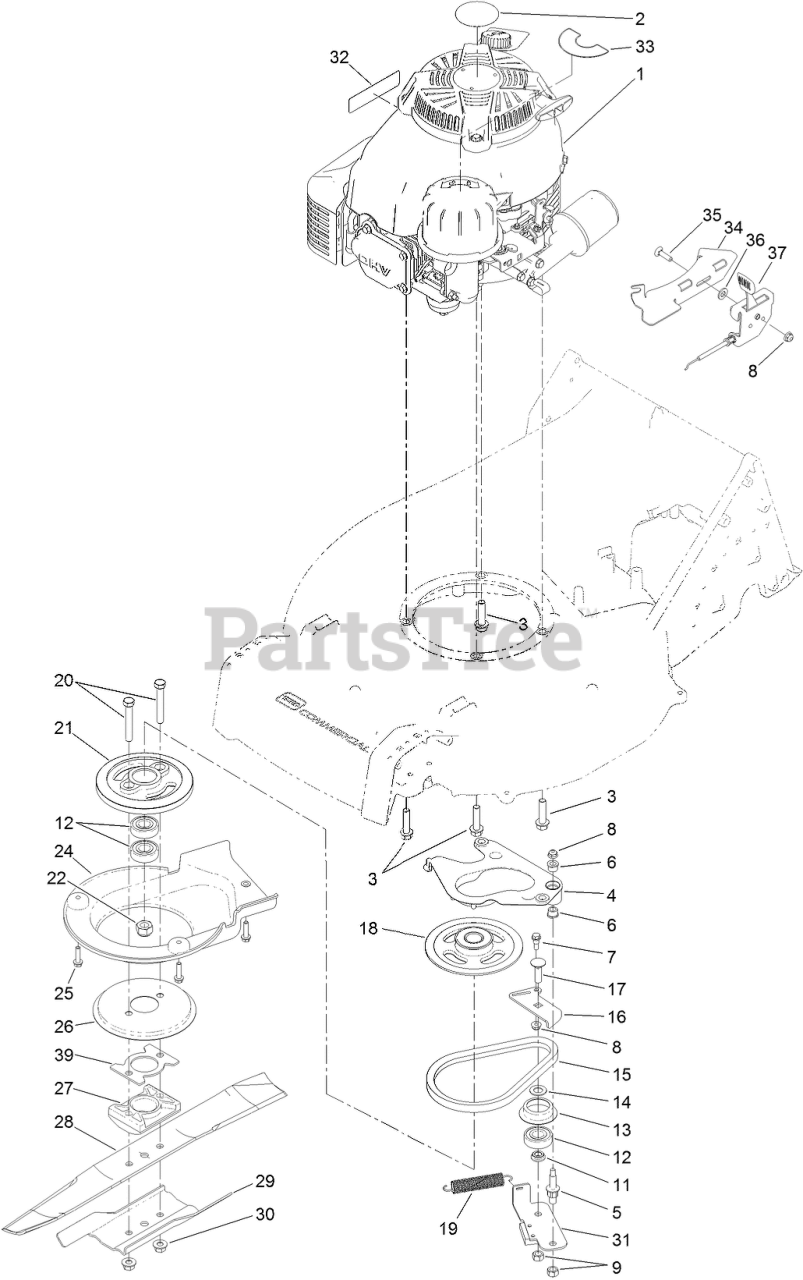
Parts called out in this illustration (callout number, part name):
1	ENGINE-KAWASAKI, FJ180V
3	SCREW-HWH
4	PLATE-ANCHOR
5	BOLT-SHOULDER
6	BUSHING-FLANGE
7	BOLT-SHOULDER
8	NUT-HF
9	NUT-HEX
11	SPACER-BEARING
12	BEARING-BALL
13	RETAINER-BELT
14	WASHER-PLAIN
15	BELT
16	PLATE-GUIDE, BBC
17	BOLT-CARR
18	PULLEY
19	SPRING-TENSION, BRAKE
20	SCREW-HH
21	DRUM
22	NUT-HEX
25	SCREW-HWHTF
26	DISC
27	SUPPORT-BLADE
28	BLADE-RECYCLING
29	ACCELERATOR-BLADE
30	NUT-FLANGE, LOCK
31	PLATE-BRAKE
32	DECAL-ARRESTER, SPARK
34	BRACKET-MOUNT, THROTTLE
35	SCREW-CARR
36	WASHER-PLAIN
37	THROTTLE
39	SPACER-DRIVER, BLADE
